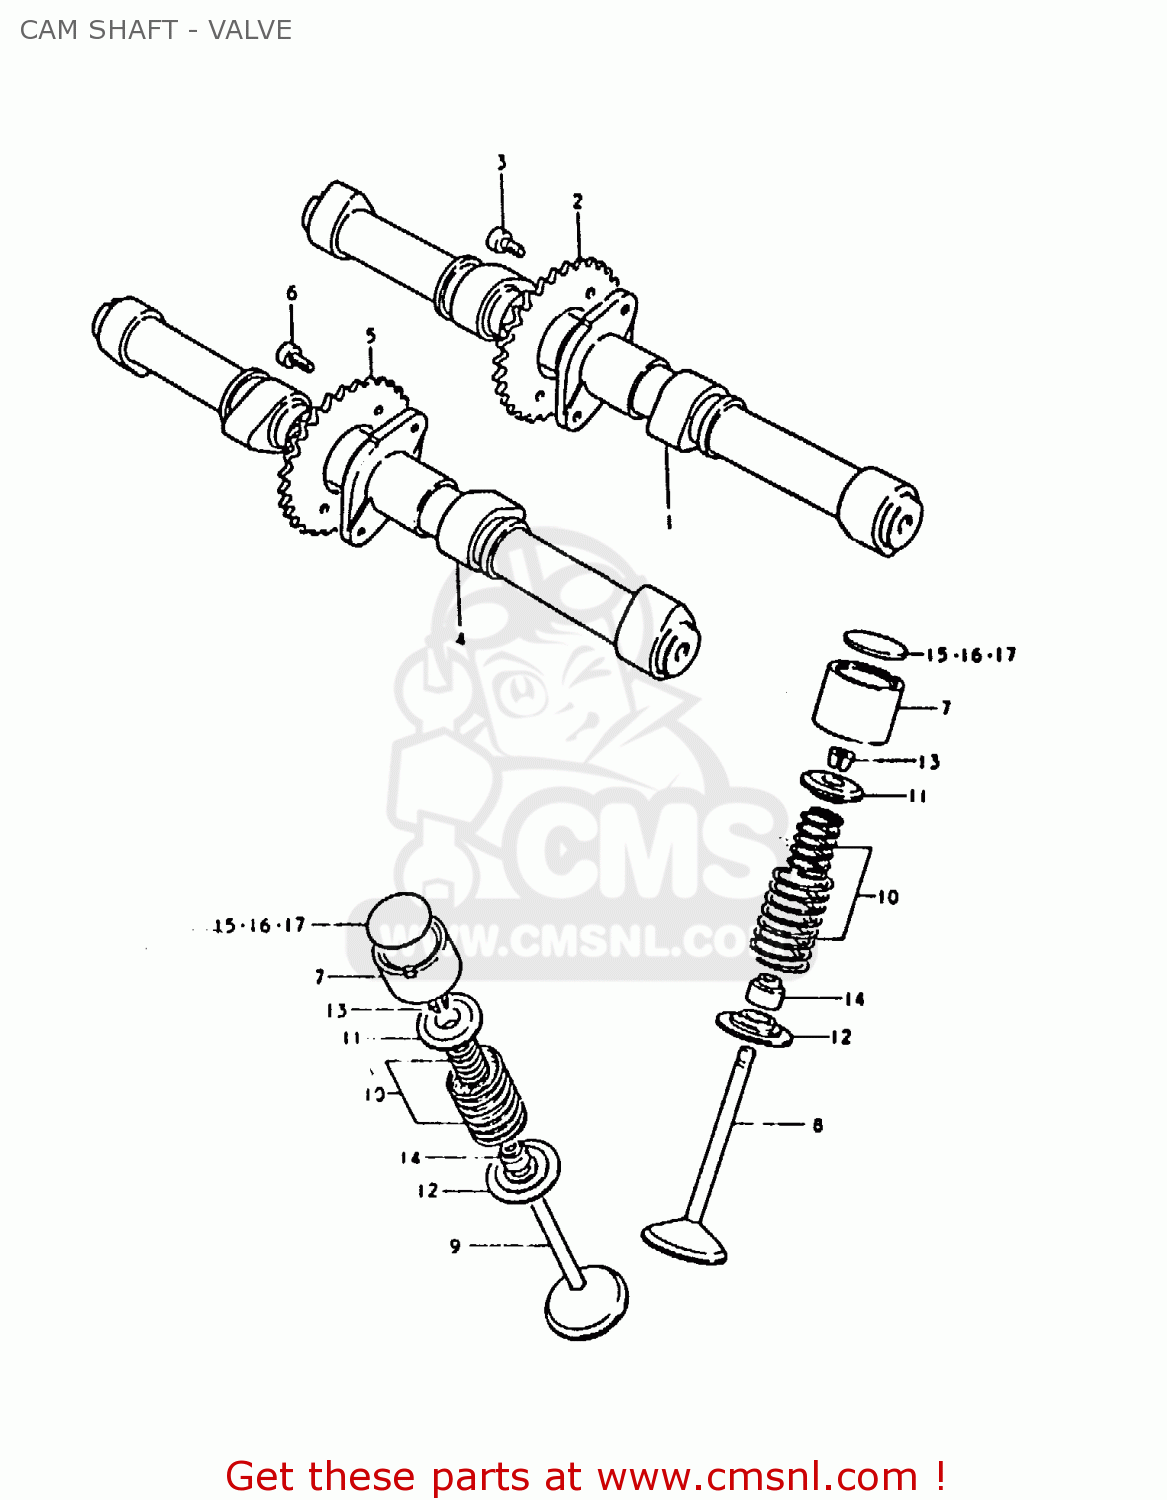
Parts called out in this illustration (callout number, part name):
1	CAMSHAFT
2	SPROCKET,INTAKE CAMSHAFT
3	BOLT 6X11
4	CAMSHAFT,EXHAUST
5	SPROCKET,EXHAUST CAMSHAFT
6	BOLT 6X11
7	TAPPET
8	VALVE,INTAKE
9	VALVE,EXHAUST
10	SPRING SET,VALVE
11	RETAINER,VALVE SPRING
12	SEAT,VALVE SPRING
13	SHIM,TAPPET
14	SEAL,OIL(7X14.4X9)
15	SHIM,TAPPET
16	SHIM,TAPPET
17	SHIM,TAPPET
